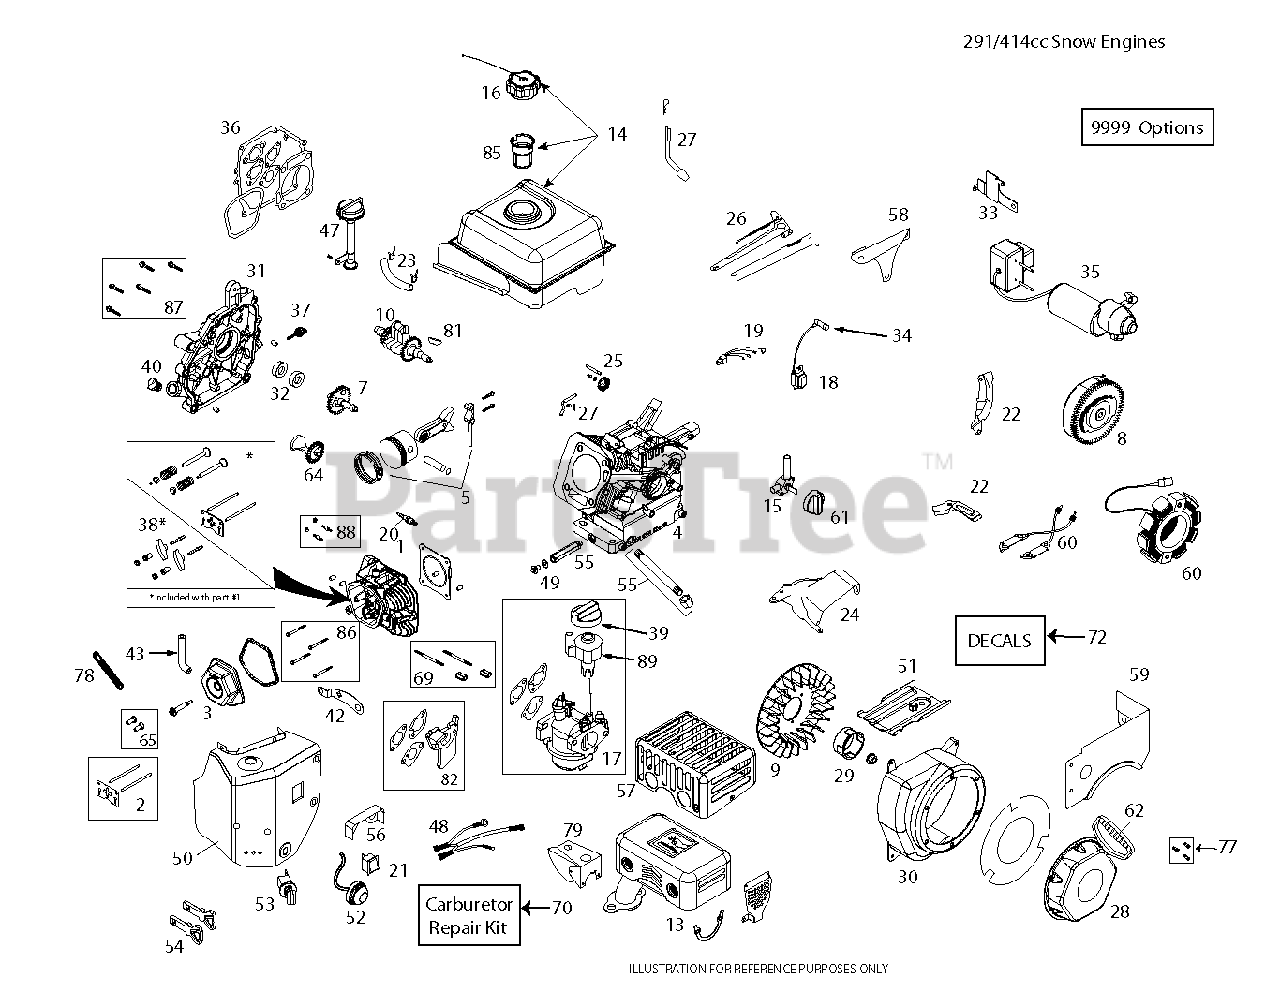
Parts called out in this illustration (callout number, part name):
1	CYLINDER.HEAD.ASSY(SK2911000)
2	PUSH ROD TAPPET KIT
3	VALVE.COVER.LCT.414CC.
4	CYLINDER ASSY SNO.LCT
5	PISTON.AND.ROD.ASSY(SK2911400)
6	CONNECTING ROD ASSY SNO.LCT
7	CAMSHAFT.LCT.291CC
8	FLYWHEEL.EL.ST.SKSNO2401.1
9	FLYWHEEL.FAN
10	CRANKSHAFT LCT.SKSN2805.1
13	MUFFLER (SKSN2210.1)
14	FUEL TANK ASSY - SNOW (291CC)
15	FUEL.PETCOCK.SNOW(SKSN4900)
16	FUEL.TANK.CAP.SNOW(SKSN4301)
18	COIL.IGN.CDI.SKSN2403.1
20	SPARK.PLUG(SK2911550)
21	ON/OFF.SWITCH.SNOW(SKSN4403)
22	SHIELD.U/FYWHL.CHARG(SKSN4604)
23	FUEL HOSE KIT
24	TOP.SHIELD.LCT.
25	GOVERNOR.GEAR.ASSY(SK2912900)
26	GOVERNOR.ARM.ASSY.(SKSN2502)
27	GOVERNOR.SHAFT.(SK2913100)
28	RECOIL.START.ASSY.(SKSN2600)
29	STARTER.CUP.SMALLSNOW(SKSN2601
30	BLOWER HOUSING.BLK ES LCT 291
31	CRANKCASE.COVER.ASY(SK2913600)
32	OIL.SEAL.KIT(SK2913900)
33	SWITCHBOX BRACKET ES LCT 291 S
34	SPARK.PLUG.BOOT.SNW,SKSN4691.1
35	ELECTRIC.START.ASSY(SKSN2400.2
36	ENGINE.GASKET.KIT(SK2914300)
37	DIPSTK.OIL.BLK.LCTSK4143711.1
38	ROCKER ARM KIT
39	CHOKE.KNOW.SNOW(SKSN4500)
40	NONREMVABLE.OIL.PLUG(SK4143715
42	CDI.BOX.BRKT.SNOW(SKSN4402)
43	TUBE.BREATHER.LCT.219CC/414CC
47	TUBE OIL FILL KIT.LCT SKSN4950
48	WIRE.HARNESS(SKSN4406)
49	OIL.DRAIN.PLUG
50	HEATER.BOX.ASSY.SNOW(SKSN2100)
51	SHIELD.CYLINDER.SNOW(SK4141010
52	PRIMER.BULB.ASSY(SKSN4304)
53	KEY.SWITCH.ASSY.SNOW(SKSN4401)
54	KEY SET(2 KEYS) SKSN0407.1
55	OIL PIPE DRAIN EXTENDED.LCT SK
56	SHIELD.VAPOR(SKSN4606)
57	SHIELD.MUFFLER.
58	GOVERNOR.LINK.SHIELD(SKSN2501)
59	FUEL.TANK.SKIRT(SKSN2101)
60	ALTERN.60WATT.SKSN2402.1
61	FUEL KNOB-SNOW
62	HANDLE.RECOIL.DELUXE.LCT
65	TAPPET KIT.LCT.SK2911005.1
69	STUD.CARB.MOUTING.KIT.291CC
70	CARBURETTOR REPAIR KIT 291CC/4
77	BOLT.KIT.RECOIL.LCT.ALL.ENGINE
81	KEYS.FLYWHEEL.136/291CC.5PACK
82	SPACER.CARBURETOR.291CC.LCT
85	STRAINER.FUEL.TANK.LCT.208CC
86	KIT.BOLT.CYLINDER.HEAD.(4PC)
87	KIT.BOLT.CRANKCASE.COVER.291CC
88	STUD.MUFFLER.KIT.LCT
89	KNOB LCT.SKSN5325.1 SPEED
9999	HIGH.ALTITUDE.JET.(>6,000FT)
